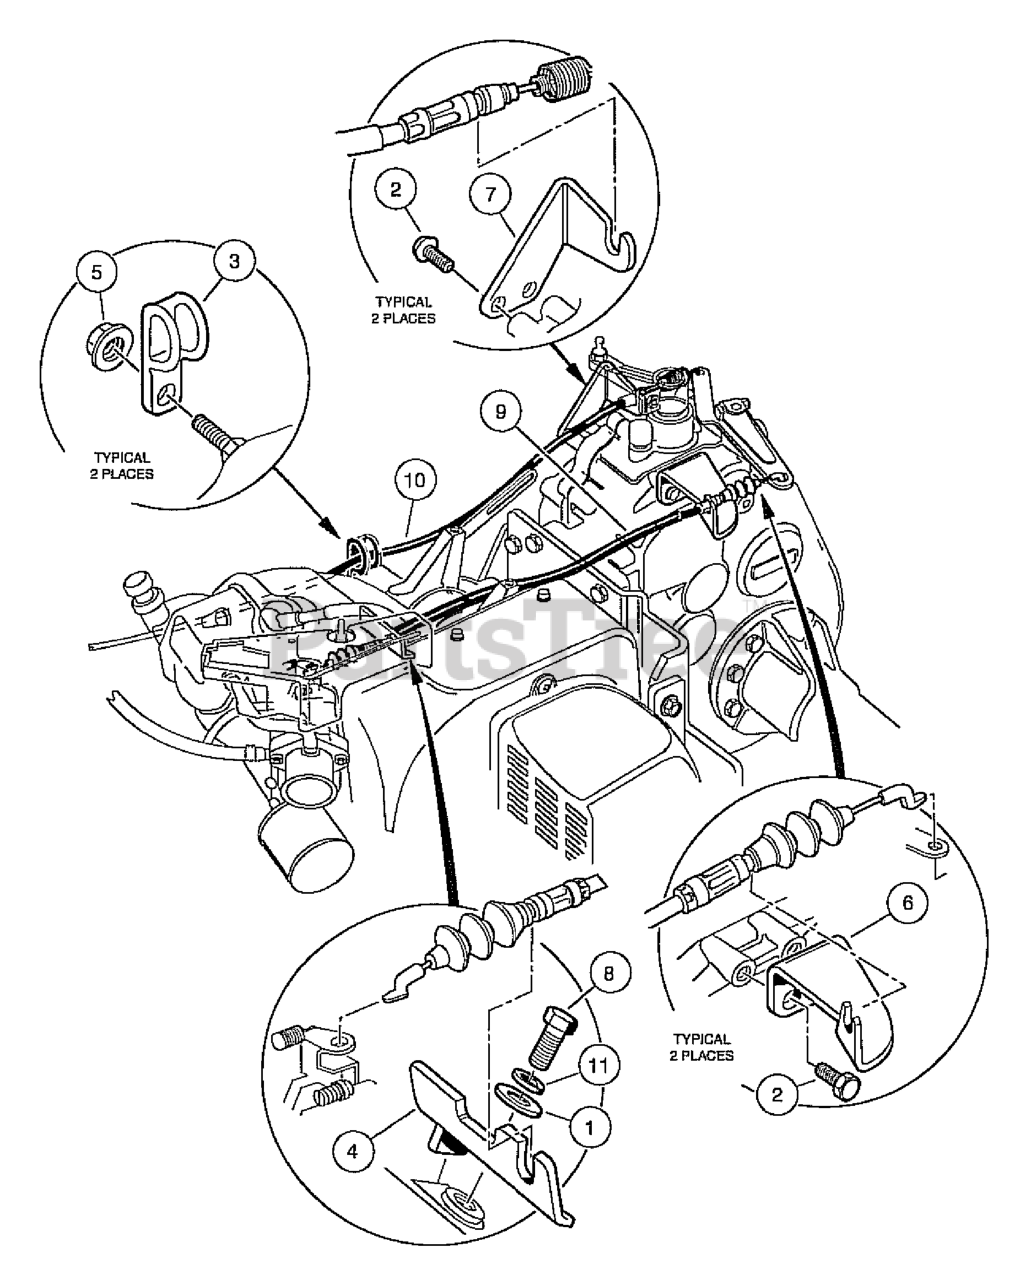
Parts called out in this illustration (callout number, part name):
1	WASHER, 5/16 FLAT
2	SCREW HX TYP TT
4	BRKT, GOV CABLE SNAP-IN
6	Bracket, Rear, Cable Snap-In
7	BRKT, REAR ACC CABLE SNAP-IN
8	SCREW, M8-125 X 22 HEX GR.8.8
9	CABLE, GOV, SNAP-IN
10	CABLE, ACC, SNAP-IN
11	LOCKWASHER, 5/16 SPLIT
